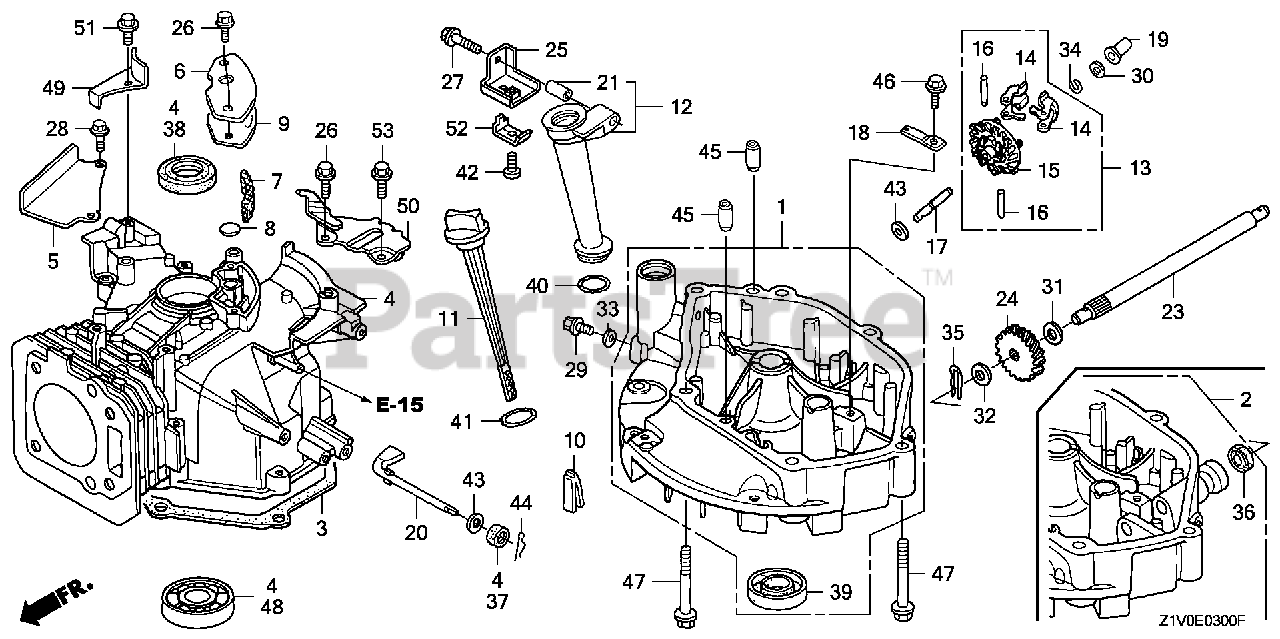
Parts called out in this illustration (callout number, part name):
1	PAN ASSY., OIL
3	GASKET, OIL PAN
4	CYLINDER ASSY.
5	PLATE, GUIDE
6	COVER, BREATHER
7	FILTER, BREATHER
8	VALVE, BREATHER
9	GASKET, BREATHER COVER
10	RUBBER, OIL RETURN
11	DIPSTICK, OIL
12	EXTENSION, OIL FILLER
13	GOVERNOR ASSY.
14	WEIGHT, GOVERNOR
15	HOLDER, GOVERNOR WEIGHT
16	PIN, GOVERNOR WEIGHT
17	SHAFT, GOVERNOR HOLDER
18	PLATE, GOVERNOR SHAFT HOLDER
19	SLIDER, GOVERNOR
20	SHAFT, GOVERNOR ARM
21	COLLAR, EXTENSION
26	BOLT, FLANGE (6X14) (CT200)
27	BOLT, FLANGE (6X32) (CT200)
28	BOLT, FLANGE (6X20) (CT200)
29	BOLT, DRAIN PLUG
30	WASHER, THRUST (6MM)
33	WASHER, DRAIN PLUG (10.2MM)
34	CLIP, GOVERNOR HOLDER
37	OIL SEAL (6X11X4) (ARAI)
38	OIL SEAL (25X38X7) (ARAI)
39	OIL SEAL (25.4X40X7)
40	O-RING (22.1X2.2)
41	O-RING (25.5X3)
43	WASHER, PLAIN (6MM)
44	PIN, LOCK (8MM)
45	PIN, DOWEL (8X14)
46	BOLT, FLANGE (6X12)
47	BOLT, FLANGE (8X50)
48	BEARING, RADIAL BALL (6205)
49	PLATE A, GUIDE
50	STAY, TANK
51	BOLT, FLANGE (6X12) (CT200)
53	BOLT, FLANGE (6X14) (CT200)
